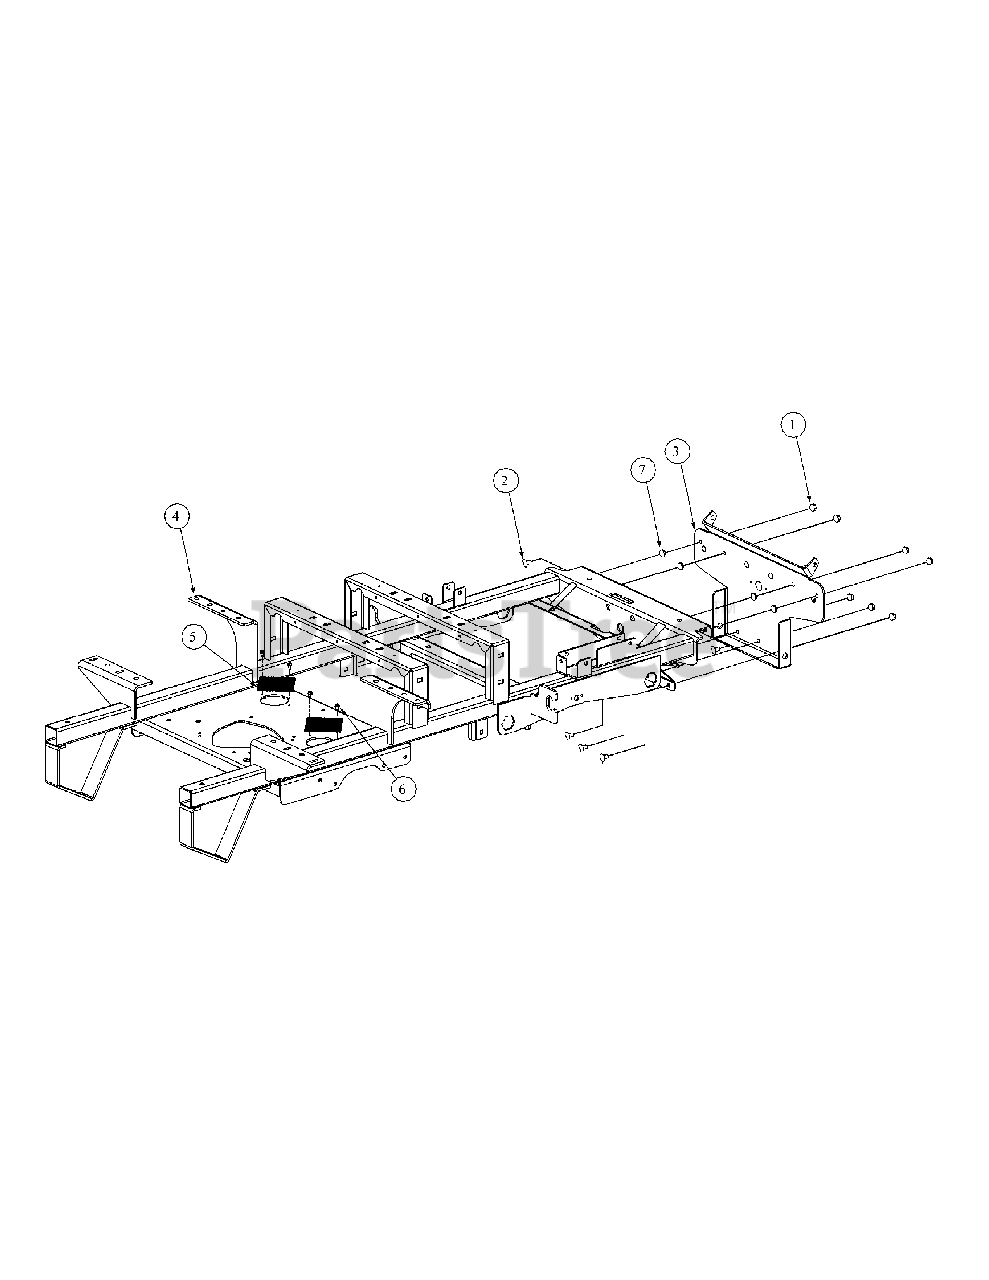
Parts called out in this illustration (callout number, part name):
1	Hex Nut, 3/8-16 Flange Lock
2	Carriage Bolt, 3/8-16 x .75 Long
3	Bracket Assembly, Frame, Front
4	Frame Assembly
5	Cover, Hydro Fan
6	Screw, TT, 1/4-20 x 0.375
7	Push Retainer, 3/8"
